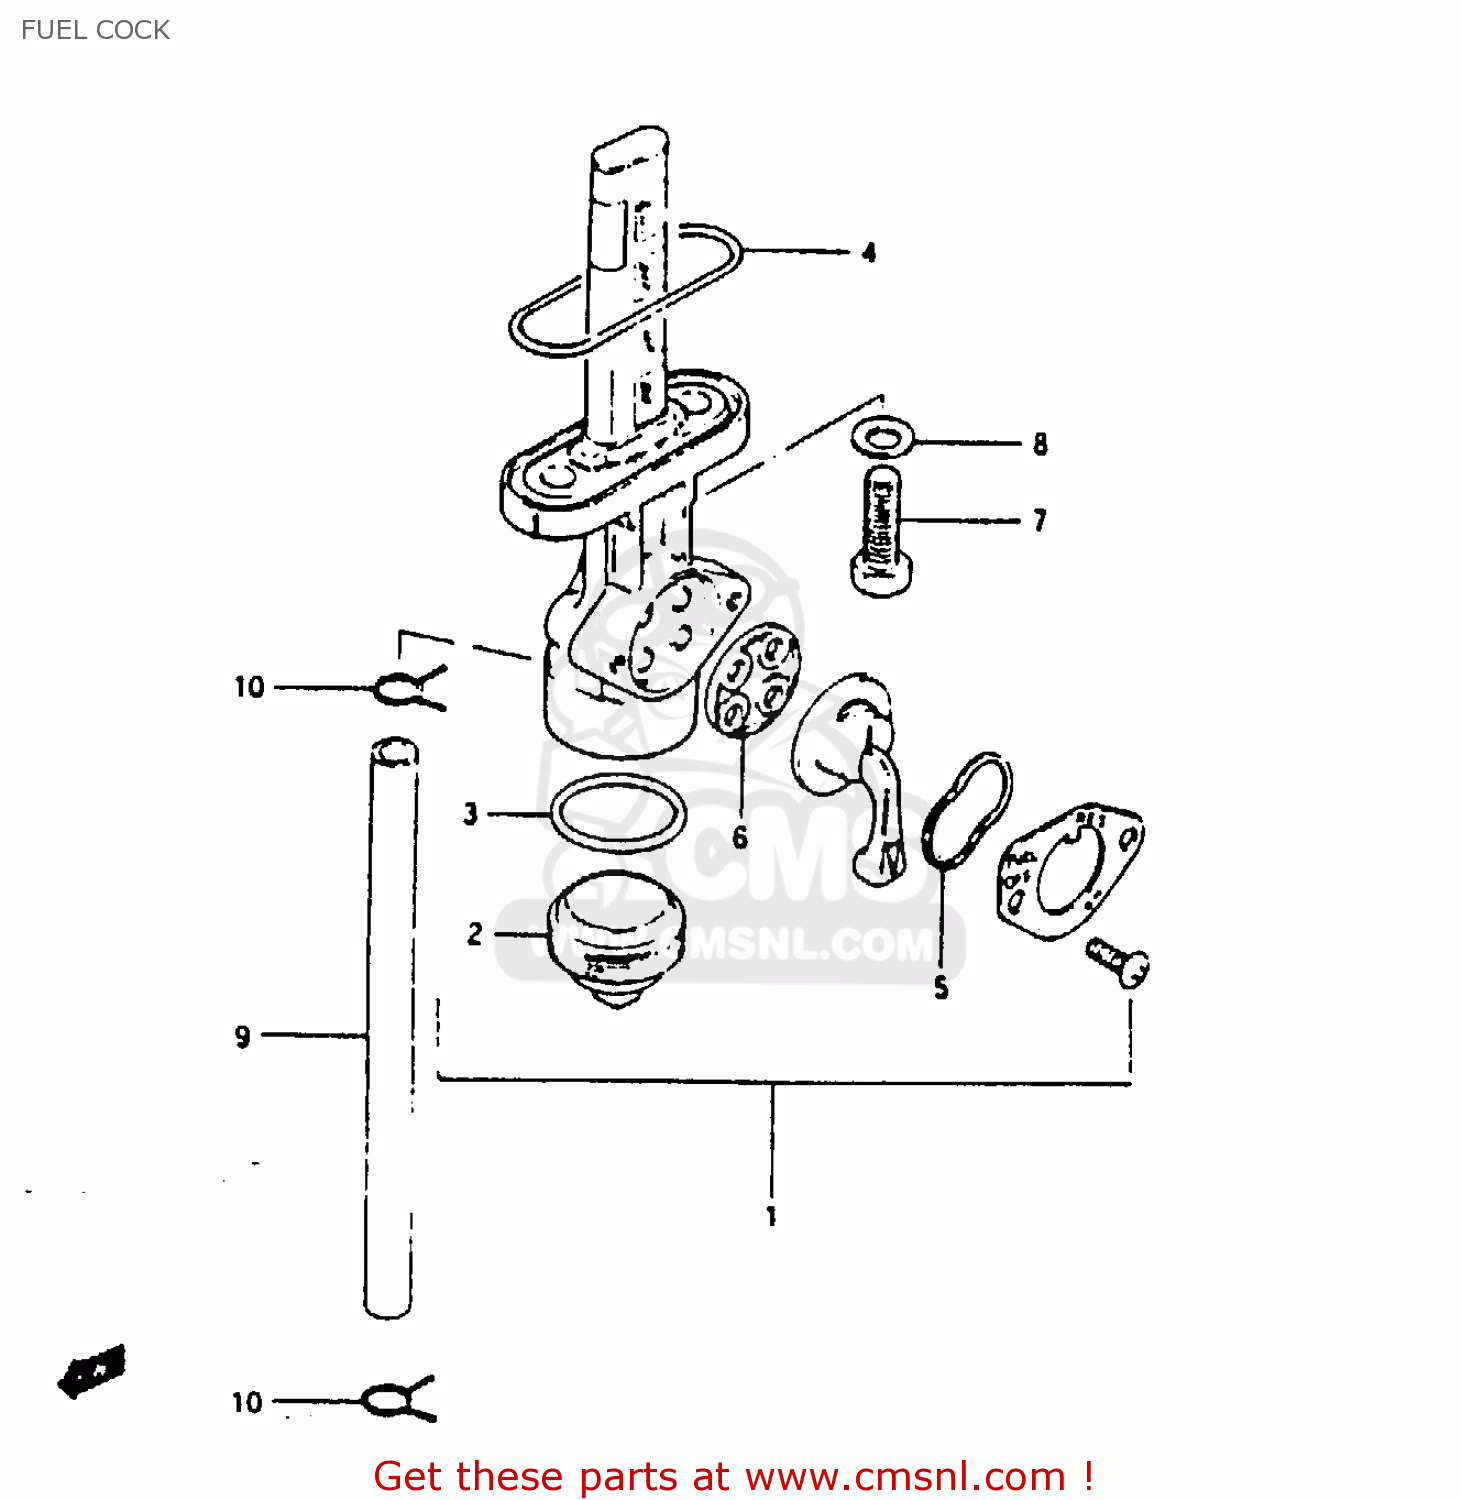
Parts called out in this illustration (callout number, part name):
1	COCK ASSEMBLY,FUEL
2	CUP,FUEL COCK
3	GASKET,FILTER (NAS)
4	O RING,FUEL COCK
5	WASHER,LEVER
6	GASKET,LEVER (NAS)
7	BOLT(6X20)
8	GASKET(6.4X11.5X0.8) (NAS)
9	HOSE(5X8.2X600)
10	CLIP
